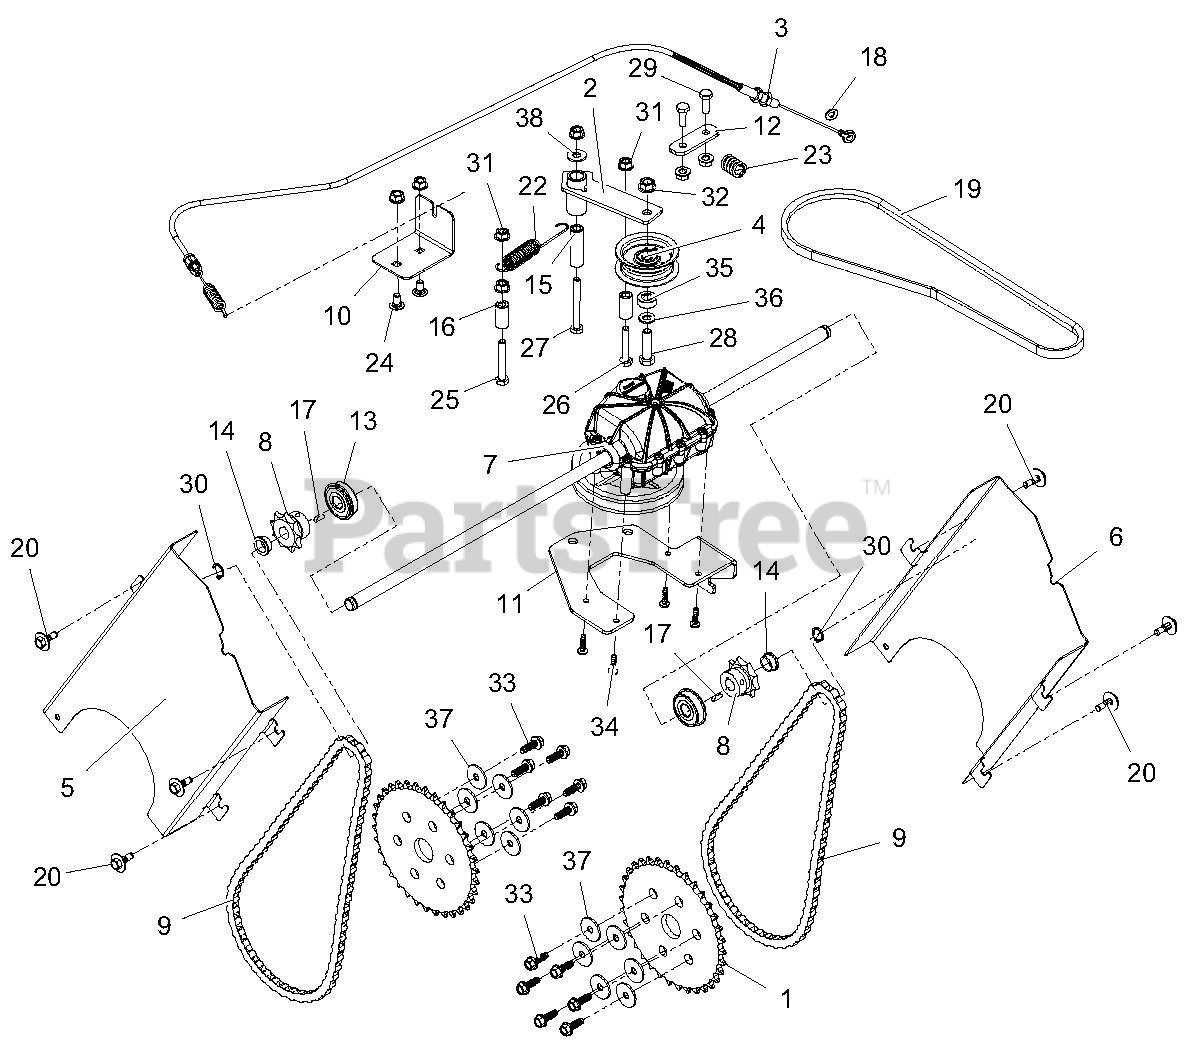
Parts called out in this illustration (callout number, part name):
1	SPROCKET, DRIVE - 41 34T FLAT
2	WLDMT, IDLER ARM
3	CABLE, TRACTION
4	IDLER, FLAT - 2.00"
5	GUARD, CHAIN - RIGHT APV
6	GUARD, CHAIN - LEFT APV
7	TRANS, DRIVE - GT MA502
8	SPROCKET, DRIVE - 41 9T #404KW
9	CHAIN, ROLLER - #41 64 PITCHES
10	MOUNT, CABLE - APV TRACTION
11	MOUNT, TRANS - APV
12	PLATE, RETAINER - APV TRANS
13	BRG, BALL .501 x 1.38 x .438 SEALED
14	BSHG, FLANGE .500 x .625 x .270 x .750
15	BSHG, SLV .265 x .505 x 1.665
16	BSHG, SLV .265 x .505 x .995
17	KEY, WDRF .125 x .50 x .20 (HRDEND)
18	NUT, PUSH .25 x .50 O.D.
19	V-BELT, 3LWRAPPED CLUTCHING (NO RUBBER BLEED THRU)
20	SCR, TAP .25-20 x .5 CAPTIVE
22	SPRG, EXTENSION
23	SPRG, COMPRESSION
24	BLT-RDHDSQNK .25-20 x .50 G5 Y
25	BLT-HEX .25-20 x 1.75 GR5 YWZC
26	BLT-HEX .25-20 x 1.50 GR5 YWZC
27	BLT-HEX .25-20 x 2.25 GR5 YWZC
28	BLT-HEX .31-18 x 1.25 GR5 YWZC
29	BLT-HEX .25-20 x .75 GR5 YWZC
30	RG-RTNG-EXT .500 x .050
31	NUT, LK-TOP-FLG .25-20 YWZC
32	NUT, LK-TOP-FLG .312-18 YWZC
33	SCR-HEX .25-14 x .75 YWZC
34	SCR-TAP #10-14 x .75 PLASTITE BLZC
35	BSHG, FLG .315 x .500 x .358 x .281
36	WSHR-FL-STL .323 x .625 x .062 YWZC
37	WSHR-FL-STL .281 x 1.000 x .063 YWZC
38	WSHR-FL-STL .312 x .734 x .065 YWZ
